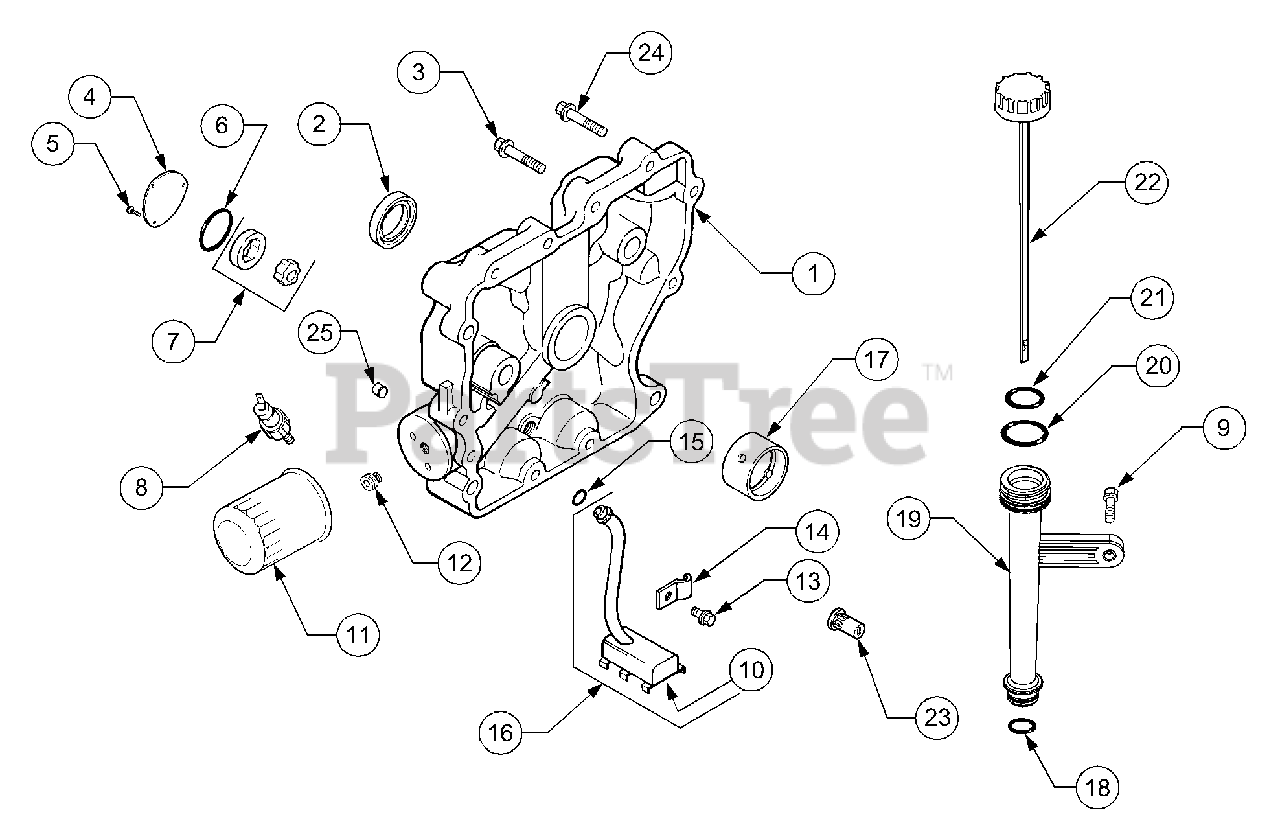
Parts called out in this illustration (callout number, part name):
1	Plate Assembly, Closure
2	Seal, Oil (PTO End)
3	Screw, Closure Plate, M8x1.25x45
4	Cover, Oil Pump
5	Screw, Oil Pump Cover, M5x.8x16
6	O-Ring, Oil Pump
7	Pump Assembly, Oil
8	Switch, Oil Pressure
9	Screw, Hex Flange M5 x 0.8 x 16
10	Pick-up, Oil Screen
11	Filter, Oil
12	Nipple, Oil Filter
13	Screw, Oil Pick-Up, M5 x .8 x 16
14	Clip, Oil Tube
15	O-Ring, Oil Pick-Up
16	Kit, Oil Pick-Up
17	Bearing, Thrust
18	O-Ring, Lower Oil Fill Tube
19	Tube, Oil Fill
20	O-Ring, Upper Oil Fill Tube
21	O-Ring, Dipstick Cap
22	Cap/Dipstick, Oil Fill
23	Valve, Oil Pressure Relief
24	Screw, Hex Flange M8 x 1.25 x 45
